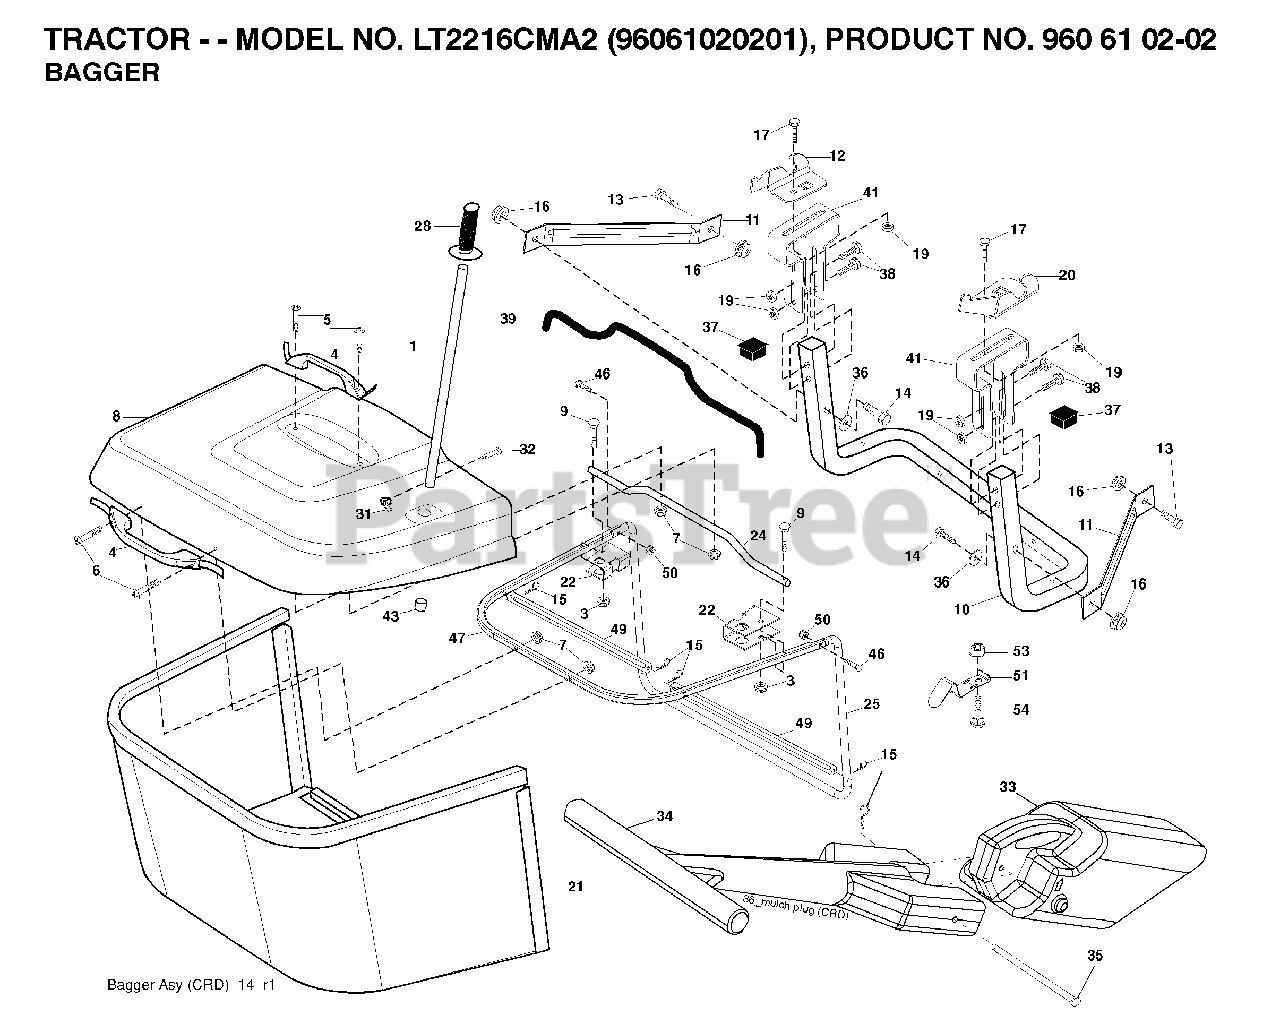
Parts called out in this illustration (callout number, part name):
1	TUBE HANDLE
3	NUT T
5	SCREW.PAN.HEAD
11	BRACKET
14	BOLT-HEX EAK
15	RETAINER-SPRNG RB
16	NUT LOCK FLG 3/8-16 UNC
17	BOLT
19	NUT LOCK HEX FLANGE 5/16-18
20	BRKT.PIVOT.RH.CRD
21	BAGGER.ASM.CRD.2007
22	BRACKET
24	TUBE
28	GRIP.HANDLE.BLACK
31	RETAINER CLIP
32	RIVET,DRILLED
33	PLUG
35	PIN
38	BOLT.5/16-18X2.5
39	SEAL.BAGGER.CRD
41	BRKT, BAGGER
43	PLUG, TUBING END
46	BOLT.CARRIAGE.5/16-18
50	NUT.71038.31-18.HEX.NYLOCK
53	NUT
54	BOLT
